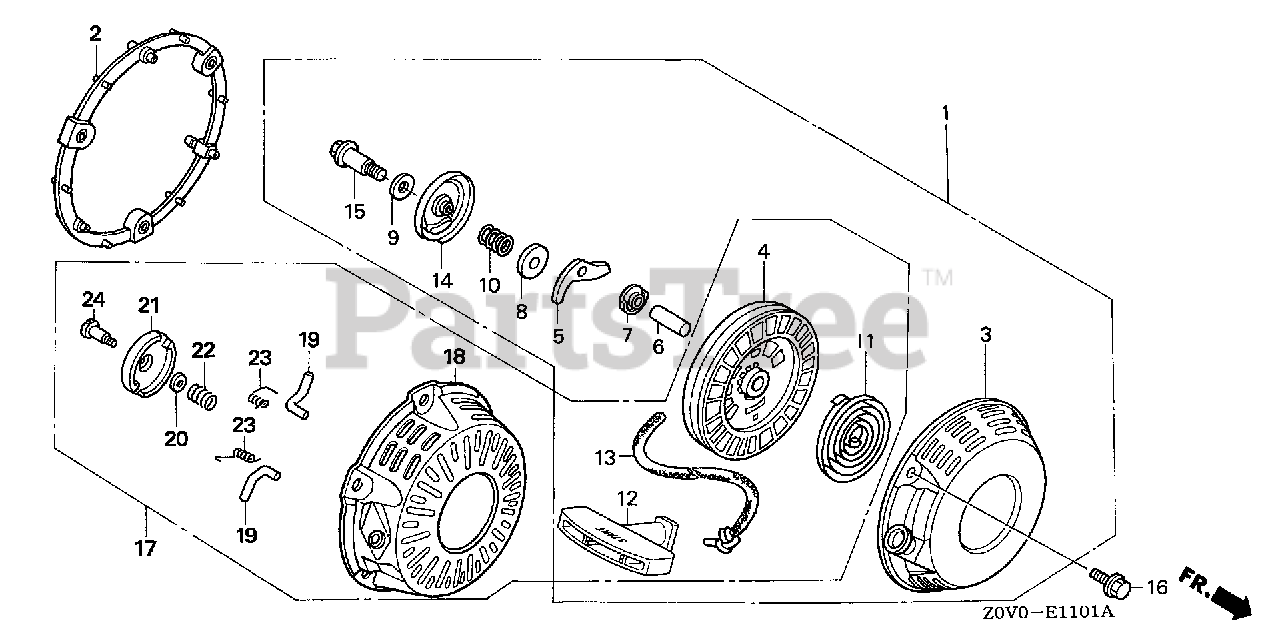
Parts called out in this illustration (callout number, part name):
2	SPACER, RECOIL STARTER MOUNTING *NH1* (BLACK)
2	SPACER, RECOIL STARTER MOUNTING *R280R* (POWER RED)
4	REEL, RECOIL STARTER (BLACK)
11	SPRING, RECOIL STARTER
12	GRIP, STARTER
12	KNOB, RECOIL SRARTER
13	ROPE, RECOIL STARTER
16	BOLT, FLANGE (6X18)
17	STARTER ASSY., RECOIL *NH1* (BLACK)
17	STARTER ASSY., RECOIL *R280* (POWER RED)
18	CASE, RECOIL STARTER *R280* (POWER RED)
18	CASE, RECOIL STARTER *NH1* (BLACK)
19	RATCHET, STARTER
20	PLATE, FRICTION
21	GUIDE, RATCHET
22	SPRING, FRICTION
23	SPRING, RETURN
24	SCREW, SETTING
